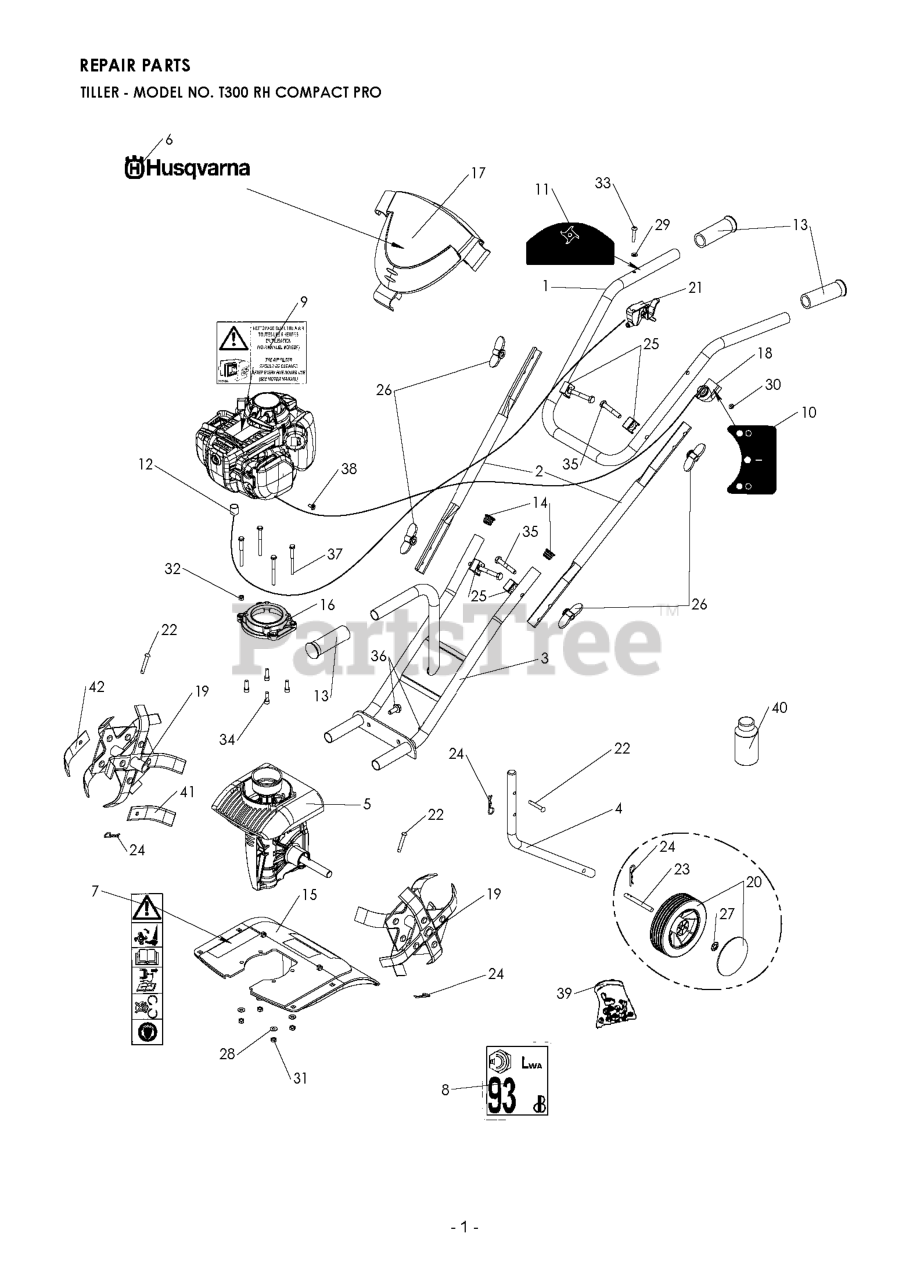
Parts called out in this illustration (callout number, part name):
5	TRANSMISSION
24	COTTER PIN
31	Blocking nut M 6 Z
